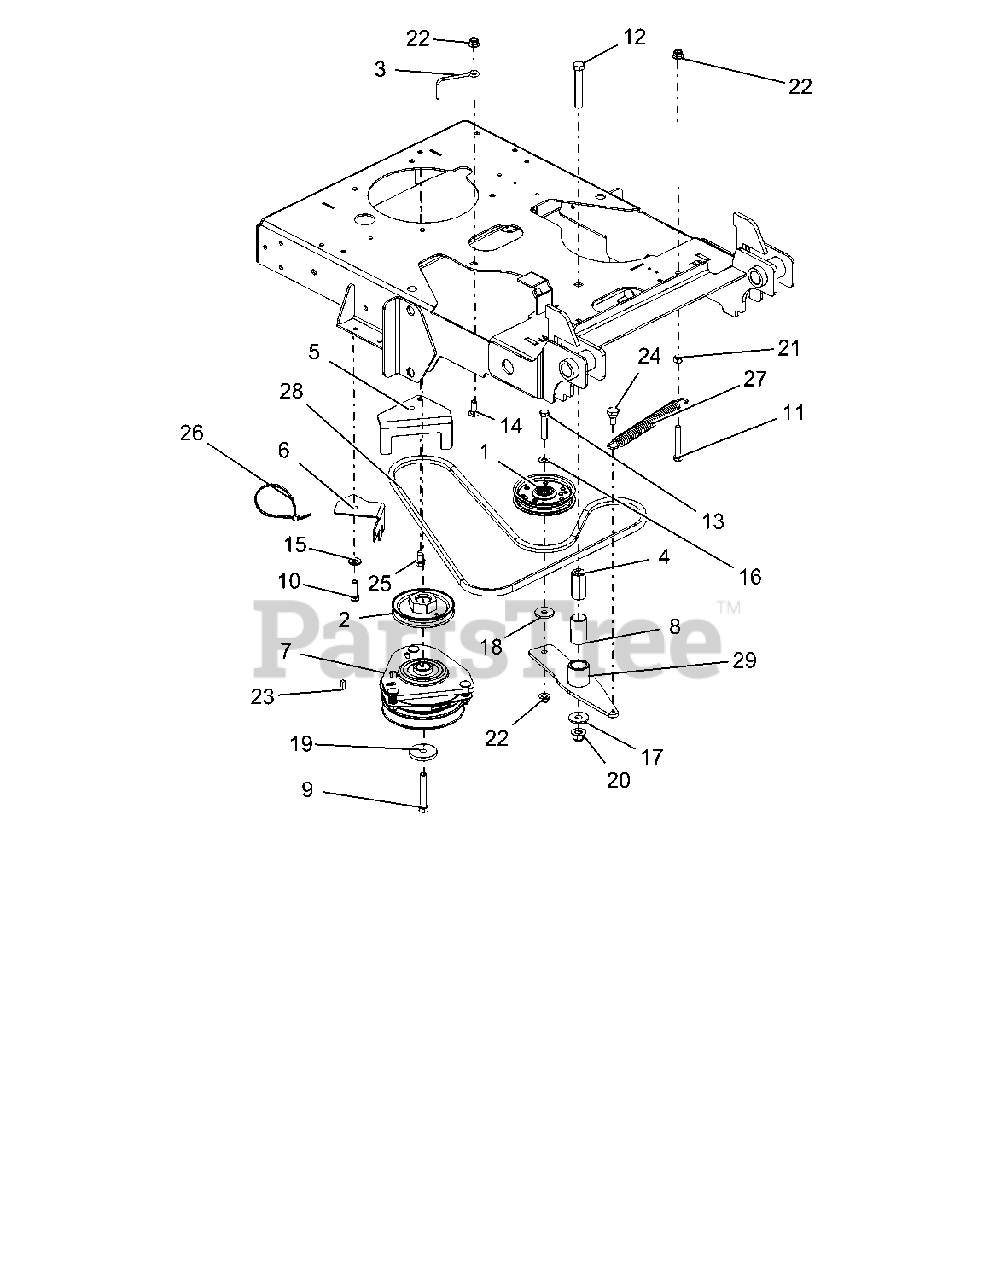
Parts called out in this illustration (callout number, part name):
1	ASM, IDLER 4"
2	PULLEY, 4.50 OD X 1.002 ENGINE - LOW FILM
3	BELT, FINGER
4	BSHG, SPCR .502X.997X2.03
5	ANCHOR, -- OGURA CLUTCH - HD
6	HD CLUTCH WIRE GUARD - BLK
8	BSHG, 1.00X1.125X1.937
9	BLT-HEX .44-20X2.75 GR5 EP80 YWZC
10	BLT-HEX .38-16X1.25 GR5 YWZC NYTORQ
11	BLT-HEX .38-16X2.50 GR5 YWZC
12	BLT-HEX .50-13X3.25 GR5 YWZC
13	BLT-HEX .38-16X2.00 GR5 YWZC
14	BLT-RDHDSQNK .38-16X1.00 G5 YWZC
15	WSHR, 3/8" SPRING DISC
16	WSHR-FL-STL.406X.812X.065 YWZ
17	WSHR-FL-STL .511X1.441x.125 YWZC
18	WSHR-FL-STL .406X1.375X.135 YZ
19	WSHR-FL-STL .469X2.00X.25 YWZC
20	NUT-LK-NYL-FLG .50-13 YWZC
21	NUT-HEX .38-16 YWZC
22	NUT-LK-NYL-FLG .38-16 YWZC
23	KEY-SQ .250X.250X.625
24	BLT, SHLDR EP .38-16X.30 HEX YZ
25	SCR-TAP .38-16X.75 HWH TR YWZ
26	CABLE, TIE 5.50 LG
27	SPRG, EXTENSION .120X.845X6.55 WLD
28	V-BELT, 4L-WRAPPED
29	HYDRO DRIVE IDLER ARM WMT
